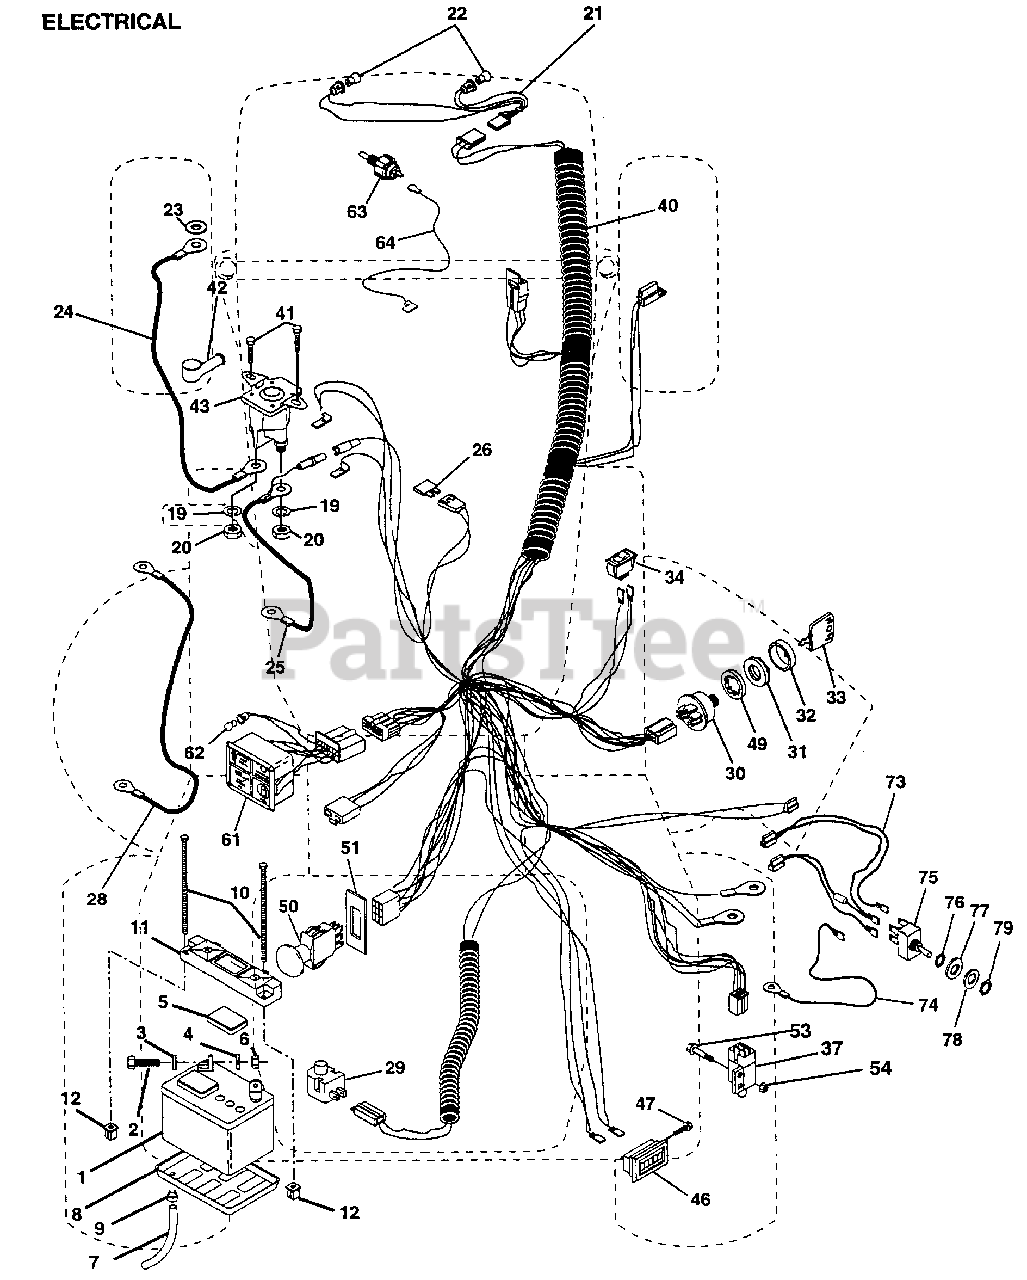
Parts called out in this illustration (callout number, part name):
2	BOLT LT
3	LOCKWASHER
4	WASHER
5	"CAP,BATTERY "
7	"DRAIN TU T, BATT"
8	"TRAY T, BATTERY"
9	HOSE CLAMP T
20	NUT
21	"HARNESS,LIGHT SOC"
22	HEADLAMP BULB
23	LOCKWASHER
24	"CABLE T, BATTERY"
25	CABLE.6GA.12.5.
26	FUSE HYT
28	CABLE T
29	SWITCH SEAT
32	COVER KEY SWITCH
33	KEY MLD GEN DELTA
34	SWITCH LT
37	SWITCH INTERLOCKT
40	HARNESS.IGN.GT.EL
41	SCREW
46	HOUR METER T
47	SCREW
49	LOCKWASHER
51	RING RETAIN PTO
53	SCREW
54	"NUT,KEPS"
61	LIGHT.PKG.ASM.
62	BULB LIGHT T
63	SWITCH OIL KOHLER
64	WIRE LEAD KOHLER
73	HARNESS ASM LIFT
74	WIRE LIFT SWI T
78	WASHER
